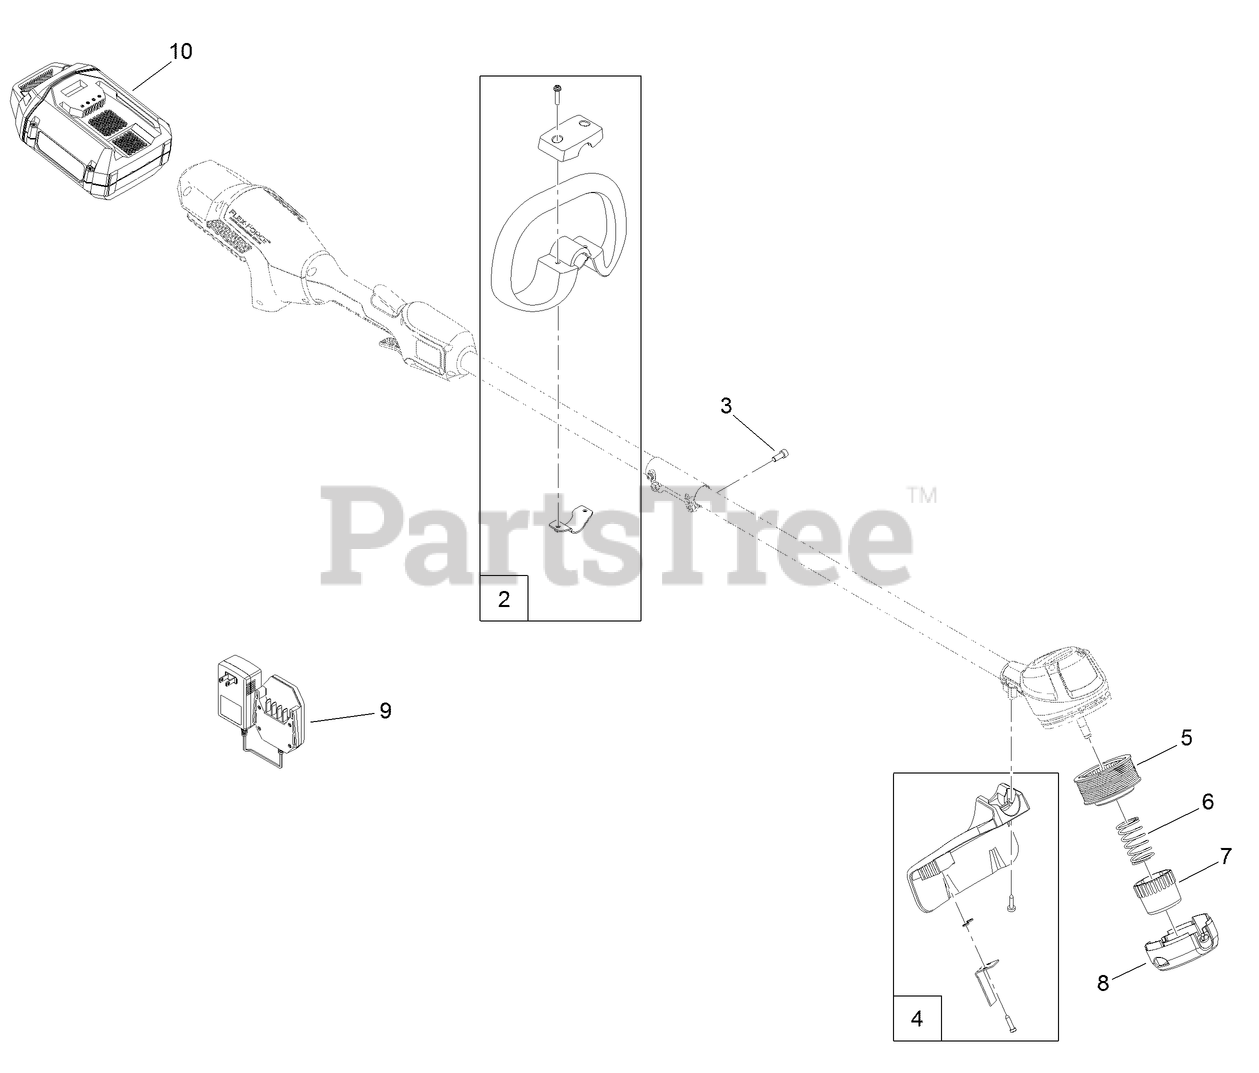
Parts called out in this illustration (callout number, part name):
2	HANDLE-TRIMMER
3	SCREW-COUPLER, SHAFT
4	SHIELD-GRASS
5	LINE-TRIMMER
6	SPRING-FEED, BUMP
7	BUTTON-FEED, BUMP
8	COVER-SPOOL
9	CHARGER-BATTERY, 60V 1 AMP
10	BATTERY-60V 2.0AH
